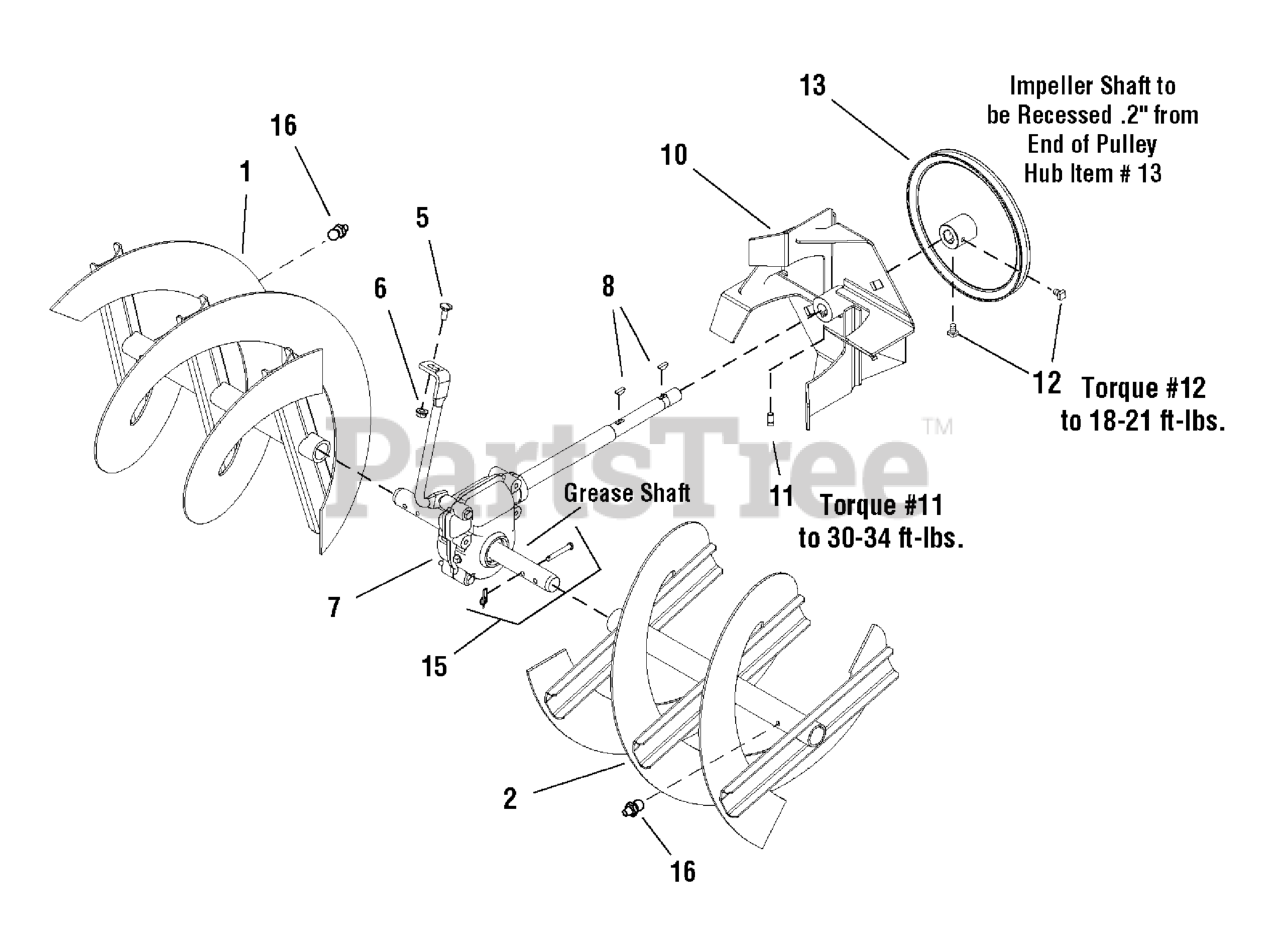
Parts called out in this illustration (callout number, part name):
1	AUGER ASSEMBLY, 32" R.H.
2	AUGER ASSEMBLY, 32" L.H.
5	CARRIAGE BOLT, 5/16-18 x 3/4 G5
6	NUT, Hex Flange Whiz Lock, 5/16-18
7	GEAR BOX ASSEMBLY
8	KEY, Woodruff
10	IMPELLER ASSEMBLY
11	SCREW, Set Square Head Cup Point, 3/8-16 x 1/2 G8
12	SCREW, Set Square Head Cup Point, 5/16-18 x 1/2 G8
13	PULLEY, 8.40 OD .752ID .720WD W/Hub
15	KIT, Shear Pin
16	FITTING, Lube, 1/4 Drive, No Check Ball
